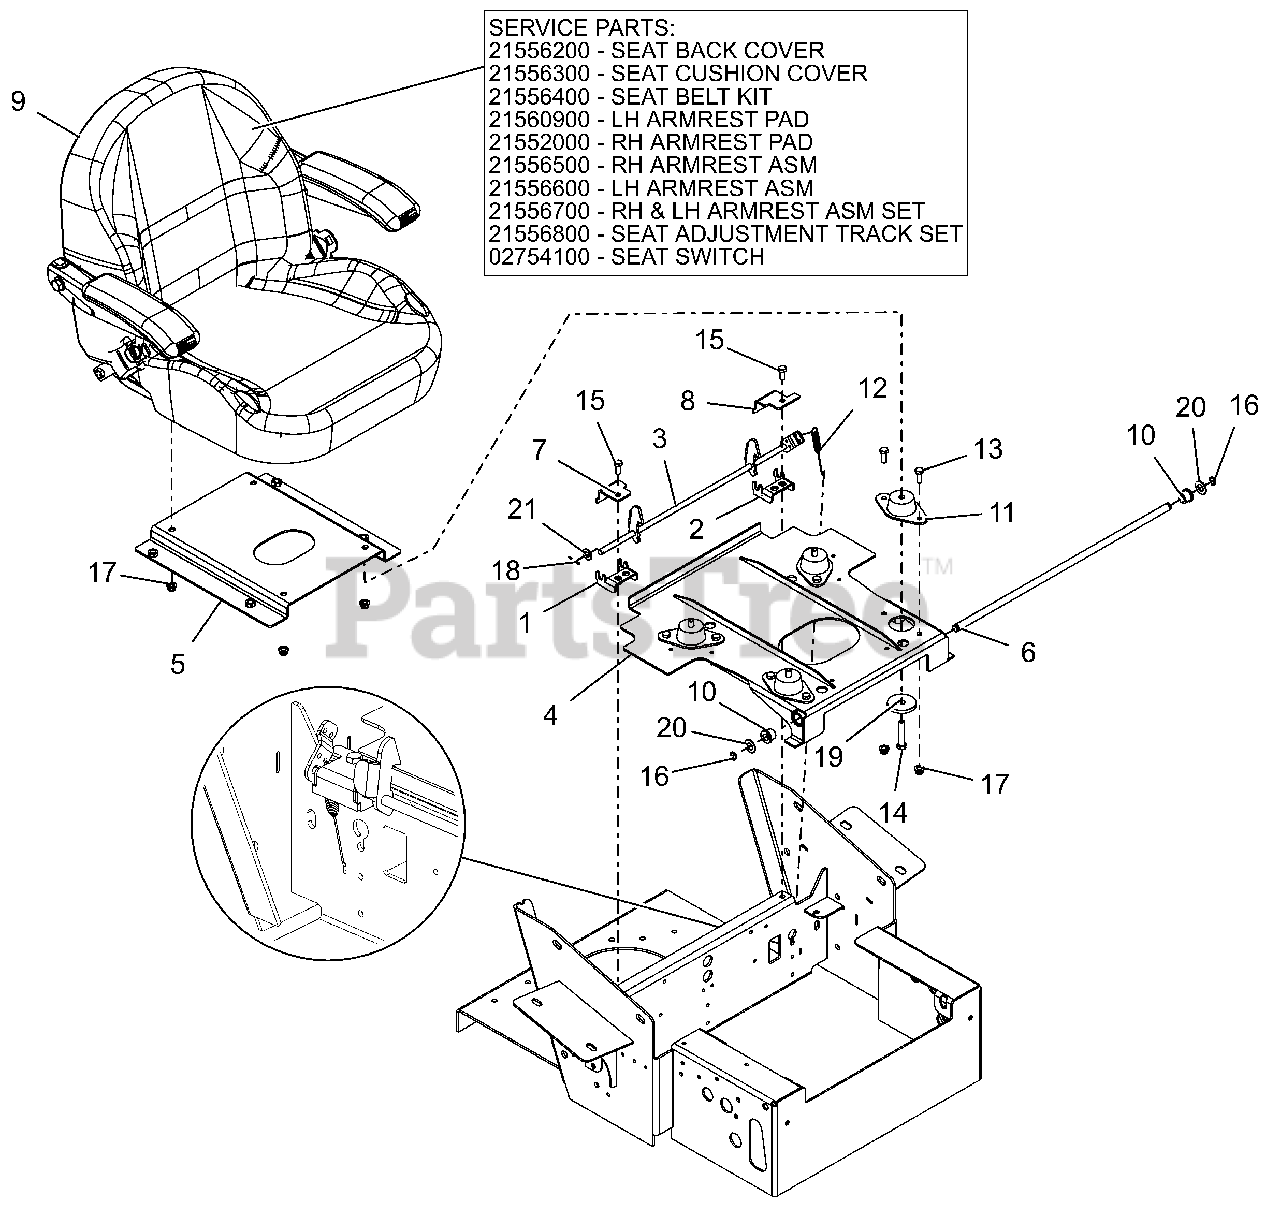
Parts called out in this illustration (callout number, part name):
1	PT100 RH SEAT LATCH MNT WMT-BL
2	PT100 LH SEAT LATCH MNT WMT-BL
3	PT100 SEAT LATCH WLDMT - BLACK
4	PT ISOLATOR MTG PLATE WMT -BLK
5	SEAT PLATE WLDMT - BLACK
6	SHAFT, PT100 SEAT PIVOT
7	PT100 RH TOP SEAT LATCH MNT-BL
8	PT100 LH TOP SEAT LATCH MNT-BL
9	SEAT, NON-SUSPENSION
9	COVER, SEAT BACK
9	COVER, SEAT CUSHION
9	KIT, SEAT BELT
9	PAD, ARMREST (HARD)
9	PAD, ARMREST
9	ARMREST, RH ASSEMBLY
9	ARMREST, LH ASSEMBLY
9	SET, RH & LH ARMREST ASSEMBLY
9	SET, SEAT ADJUSTMENT TRACK
9	SWITCH- SNAP MTG N.O.
10	BSHG, FLG .516X.750X.625X.937
11	MOUNT, FAIL-SAFE COMPRESSION
12	SG-TENS .043X.44X3.31 WLD 5.8
13	BOLT-HEX.31-18X.875 YWZC GR5
14	@BLT-HEX .38-16X2.00 GR5 YWZC
15	@BLT-HEX .31-18X.75 GR5 YWZC
16	RG-RTNG-EXT .500X.050 (SNAP)
17	@NUT-LK-NYL-FLG .31-18 YWZC
18	@PIN-CTR .09X.75 EXTPRSQCT YWZ
19	WSHR-FL-STL .469X2.00X.25 YWZC
20	WSHR-FL-STL.531X1.00X.063 YWZC
21	@WSHR-FL-STL.406X.812X.065 YWZ
